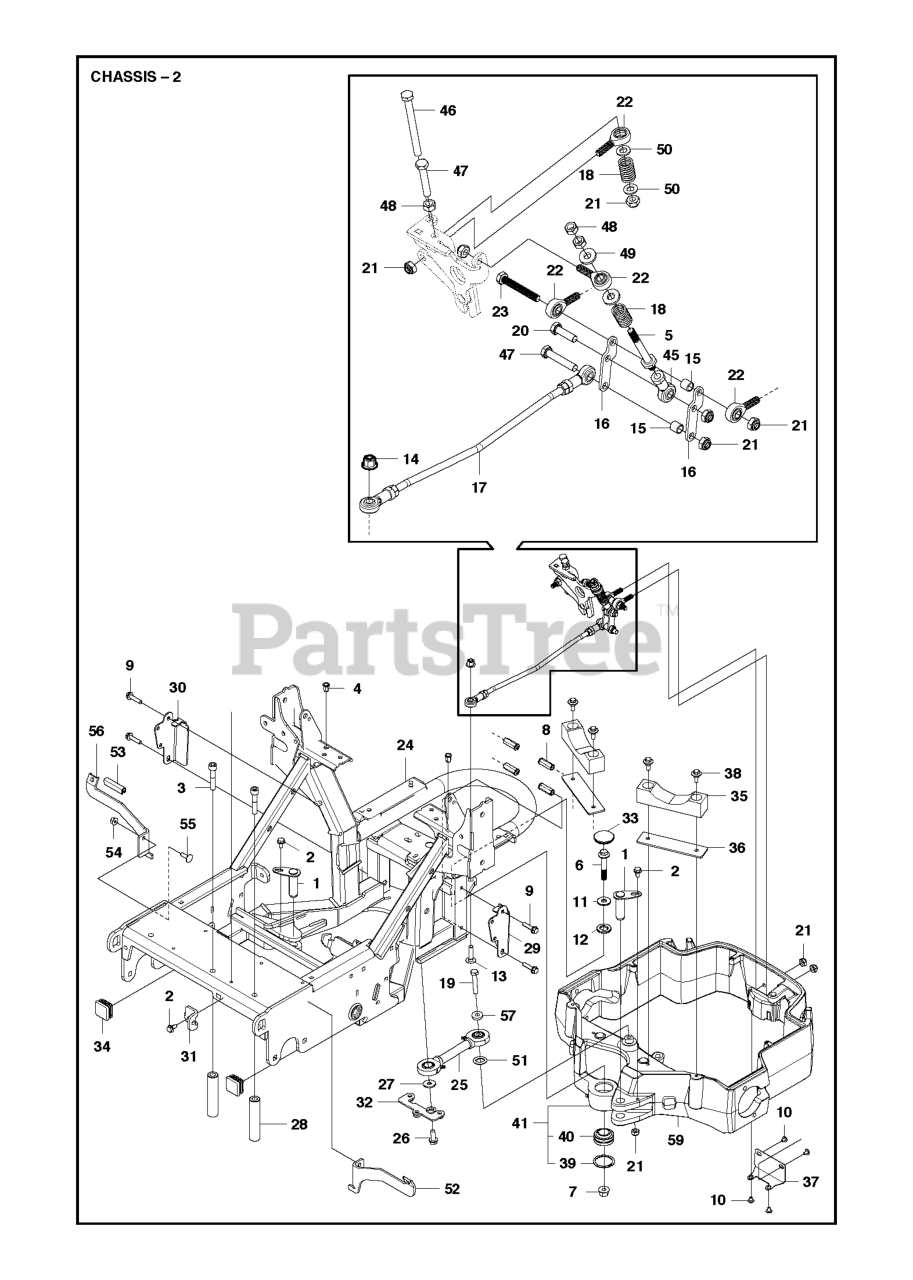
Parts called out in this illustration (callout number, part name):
33	HUB CAP PIVOT WHEEL
38	COLLAR SCREW
48	Nut
50	WASHER
54	NUT FLANGE
